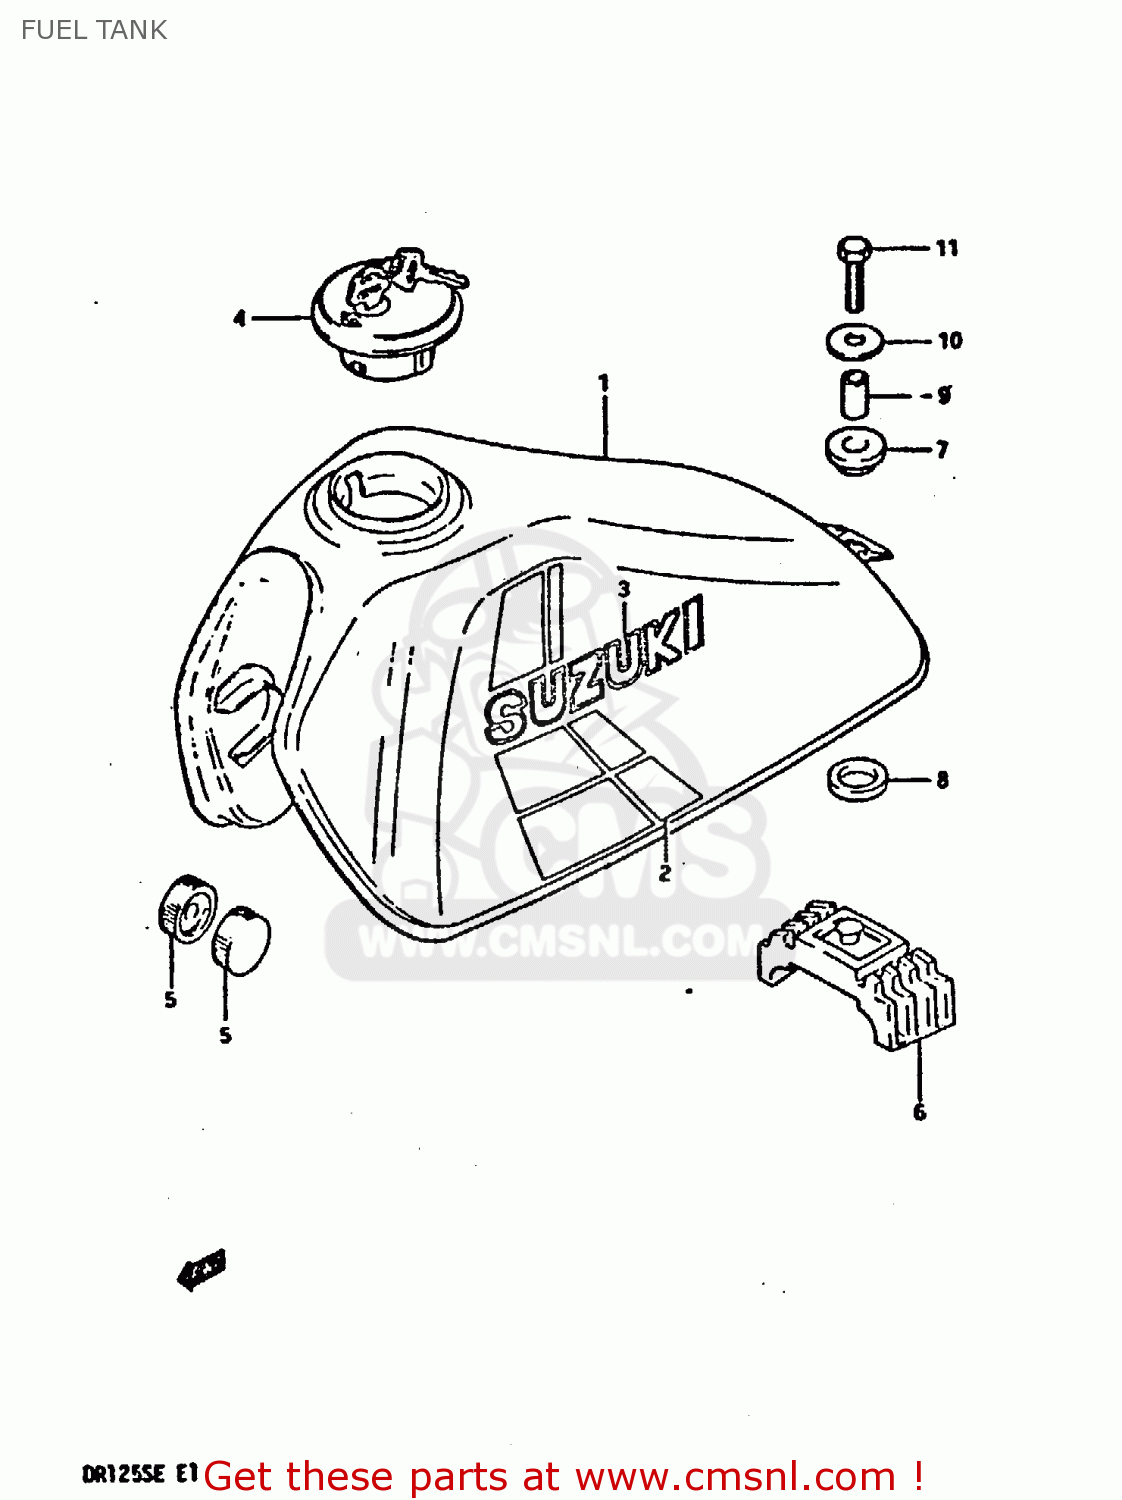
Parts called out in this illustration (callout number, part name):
1	TANK ASSY, FUEL (RED)
2	TAPE SET, FUEL TANK
3	EMBLEM
4	CAP SET,FUEL TANK
5	CUSHION
6	CUSHION,FUEL TANK
7	CUSHION
8	CUSHION
9	SPACER(8.5X12X19)
10	WASHER(104X110X2)
11	BOLT (8X30)
